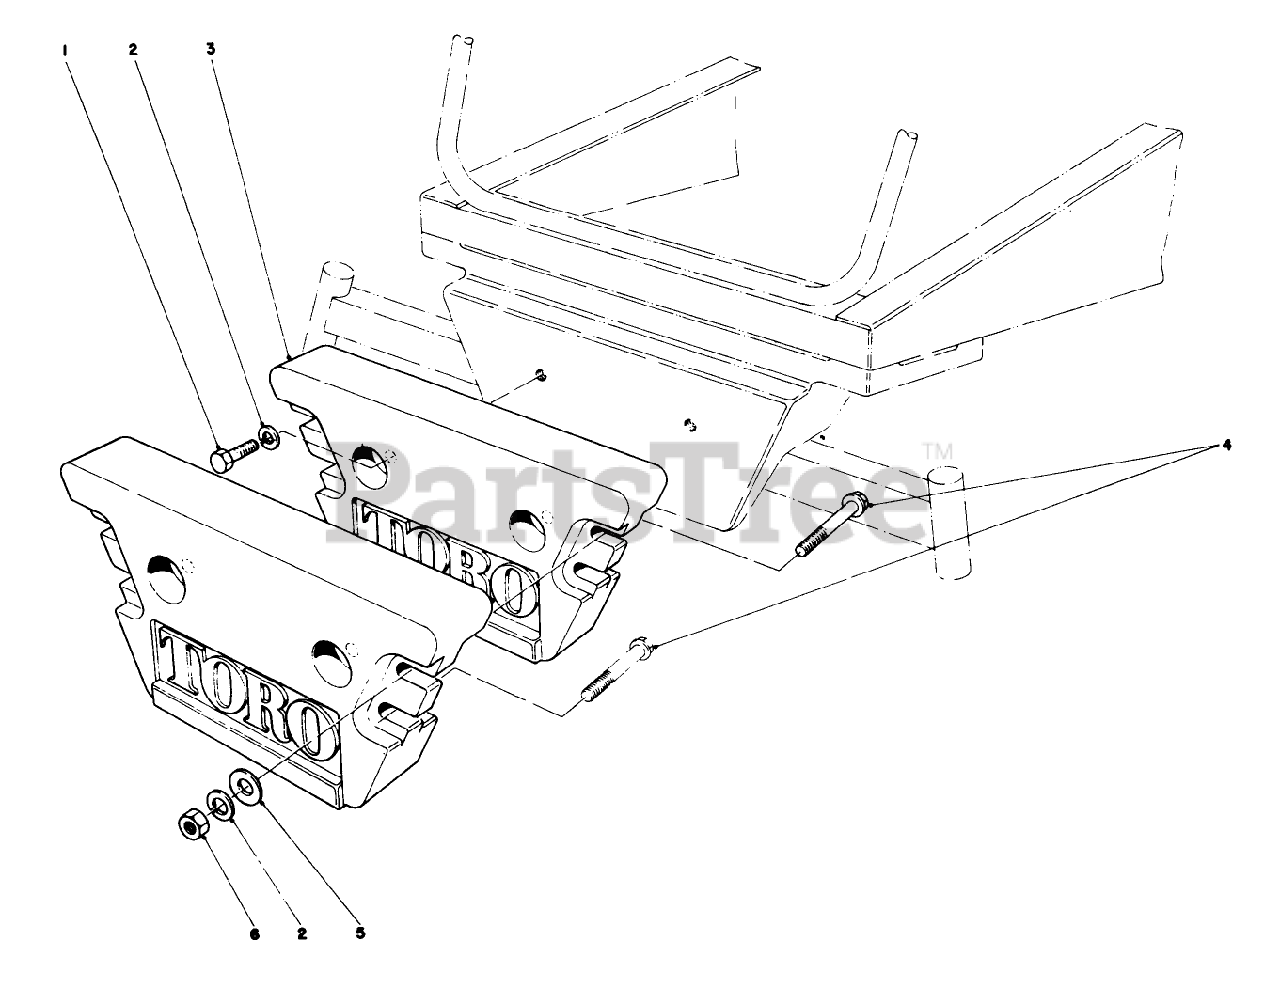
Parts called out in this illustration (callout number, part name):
1	SCREW-HH
2	WASHER-LOCK
3	WEIGHT-REAR
4	SCREW-HH
5	WASHER-FLAT
6	NUT-HH
